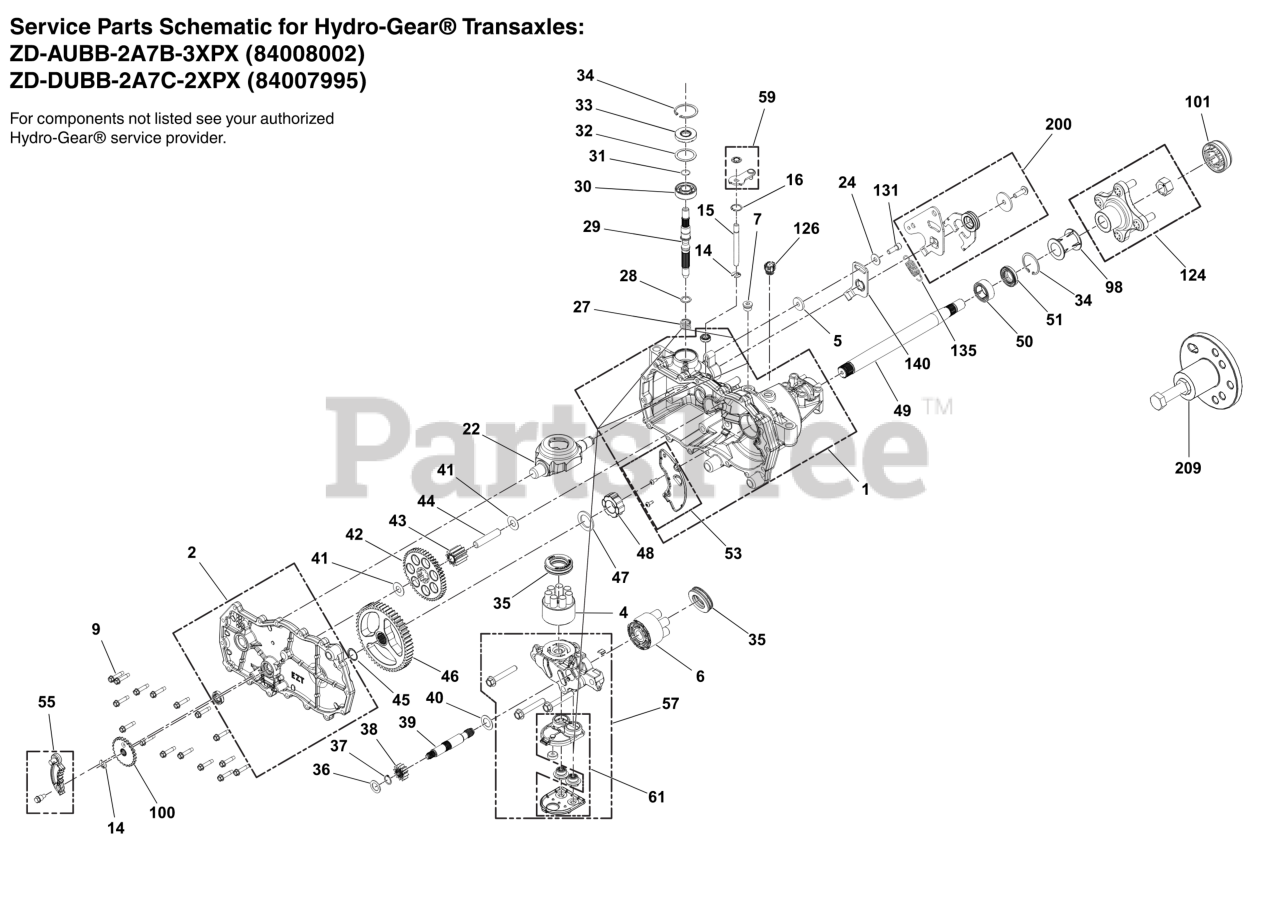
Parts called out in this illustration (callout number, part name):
1	KIT, Housing Main, RH
2	KIT, Housing, Side RH
4	KIT, BLOCK 7 PISTON
6	Cylinder Block Kit
7	PLUG, 9/16-18 STR THREAD SOCKET HEAD
9	SCREW, HEX WASHER
15	ROD, BYPASS
19	SWASHPLATE, TRUNNION
27	SPRING - HELICAL COMPRESSION
28	WASHER, Block Thrust
29	SHAFT, Input
30	BALL BRG 17MM ID X 40MM OD X 12MM
31	RING RET 67 EXT WIRE
32	SPACER (50951)
33	Lip Seal 17 x 40 x 7 PTC
33	SEAL, LIP, 17 X 40 X 7
34	Spacer
34	RING, RET 2.06 INT,
36	WASHER, .63 X 1.00 X .05 FLAT
37	RING-SNAP (44145)
39	SHAFT, MOTOR
40	WASHER, .71 X 1.16 X .04 FLAT
41	WASHER, .51 X 1.00 X .03 FLAT
43	GEAR, 10T JACKSHAFT
44	PIN, JACKSHAFT
47	WASHER, 1.018 X 1.571 X .105 FLAT
48	BUSHING, SLEEVE (INBOARD)
49	SHAFT, AXLE
52	KIT, Hydro Seal
53	KIT, EXPANSION PLATE RH
55	ASSEMBLY, Parking Brake Arm, Transmission
57	KIT, CENTER SECTION, W/FILTER - RH
58	TUBE, SEALANT
59	KIT, BYPASS ARM
61	KIT, FILTER
100	GEAR, Parking Brake, Transmission
101	AXLE CAP,
124	ASSM, HUB
126	ASSEMBLY, FITTING 9/16-18 BREATHER
131	KIT, RTN SCREWS
135	SPRING, EXTENSION (52401)
140	ARM, NEUTRAL RIGHT
200	ARM, Control Kit R.H.
209	KIT, HUB PULLER
